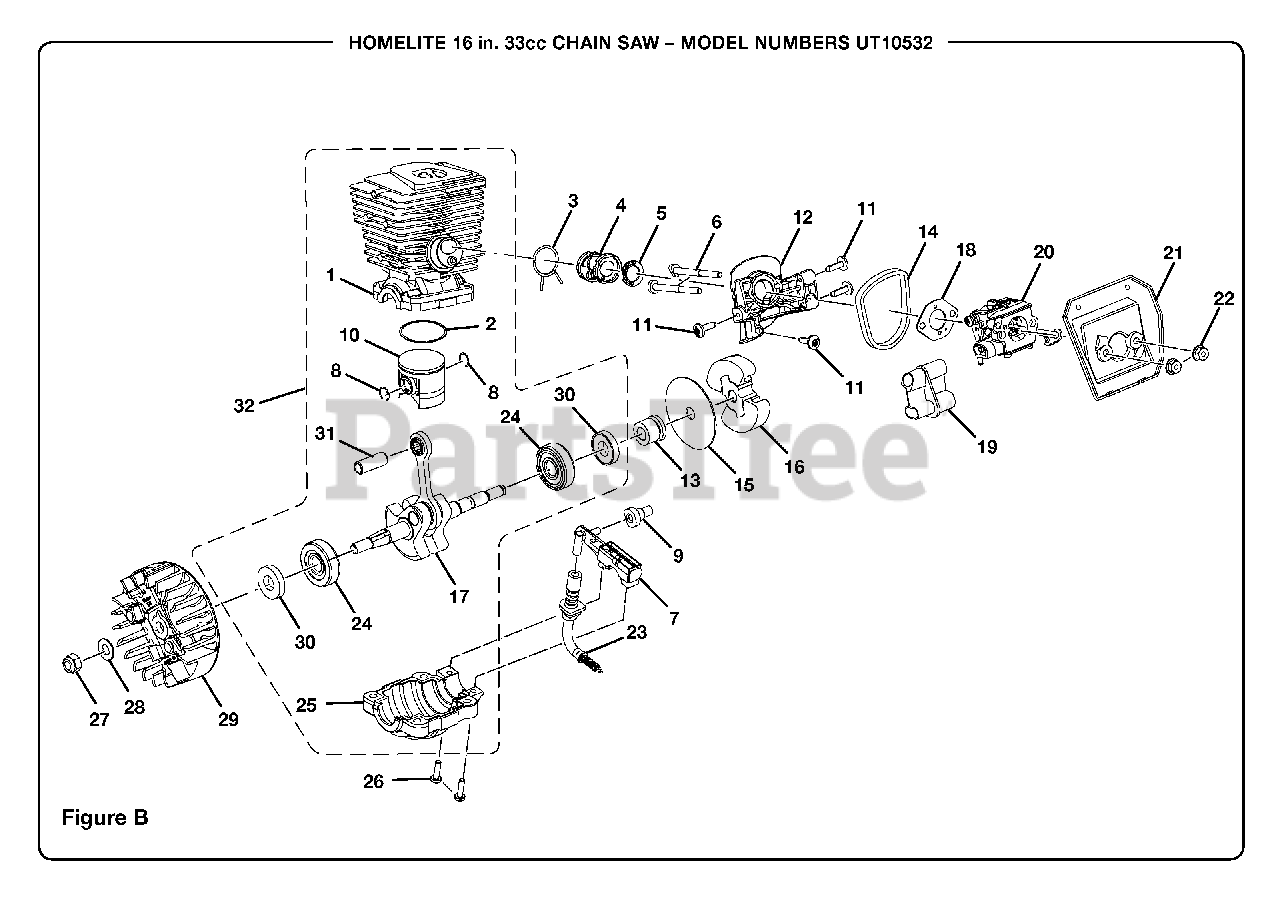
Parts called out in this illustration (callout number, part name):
2	Piston Ring
3	Wire Clamp
4	Intake Boot Rubber
5	Carburetor Plate
6	Screw (10-24 x 2-1/4 in.)
7	Oil Pump Assembly
8	Retaining Ring
9	Oil Outlet Grommet
10	Piston (33cc)
11	Screw (10-14 x 5/8 in. Torx Pan Hd.)
12	Carburetor Spacer
13	Left Hand Worm
14	Spacer Seal
15	Thrust Washer
16	Clutch Assembly
17	Crankshaft Assembly
18	Carburetor Gasket
19	Carburetor Grommet
20	Carburetor Assembly
21	Air Filter Plate
22	Flange Nut (10-24)
23	Oil Intake Tube with Spring
24	Bearing Case with Bearing
25	Crankcase
26	Screw (8-32 X 5/8 in. Pan Hd.)
27	Nut (5/16-24)
28	Flat Washer
29	Rotor Assembly
30	Shaft Seal
31	Piston Pin
32	Short Block Assembly
